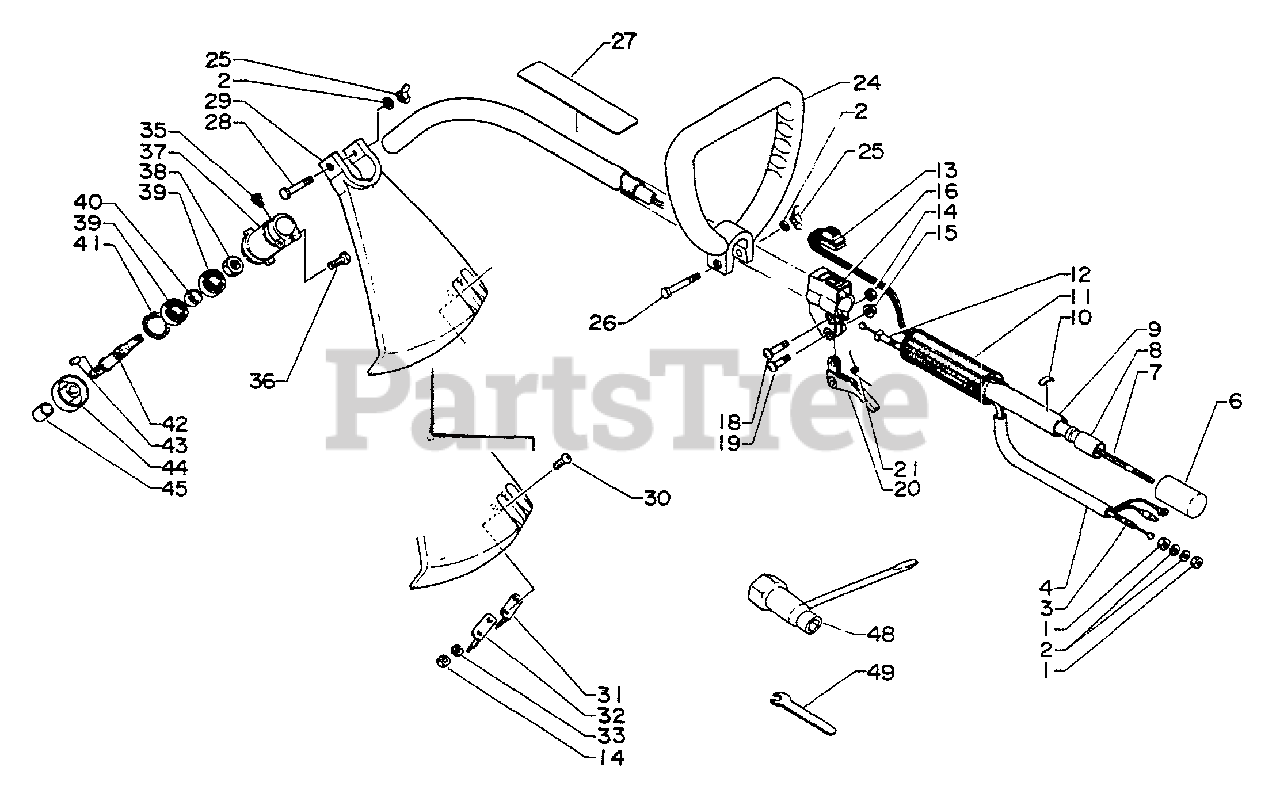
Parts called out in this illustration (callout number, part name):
2	WASHER 6.5×11.5×0.8
3	CABLE, THROTTLE
4	TUBE
7	DRIVESHAFT - FLEXIBLE
8	BUSHING
9	PIPE, MAIN
10	LABEL - ALIGNMENT
11	GRIP, HANDLE
12	GUIDE, CABLE
13	IGNITION SWITCH ASSY
14	NUT M5
15	LOCKNUT - 5
16	BRACKET, THROTTLE
18	SCREW 5×28
20	TRIGGER, THROTTLE
21	SPRING, THROTTLE
24	HANDLE ASSY
25	NUT, WING 6
26	BOLT - 6×40
27	LABEL - CAUTION
28	BOLT - 6×50
29	SHIELD
30	SCREW 5×14
31	KNIFE, TRIMMER LINE
33	WASHER, SPRING 5
35	SCREW 4×10
36	BOLT - 5×25
37	CASE, GEAR
38	NUT 12 L.H.
39	BEARING, BALL 6001 DDU
41	RING, SNAP 28
42	SHAFT, GEAR
44	PLATE, ADAPTER - UPPER
48	WRENCH
